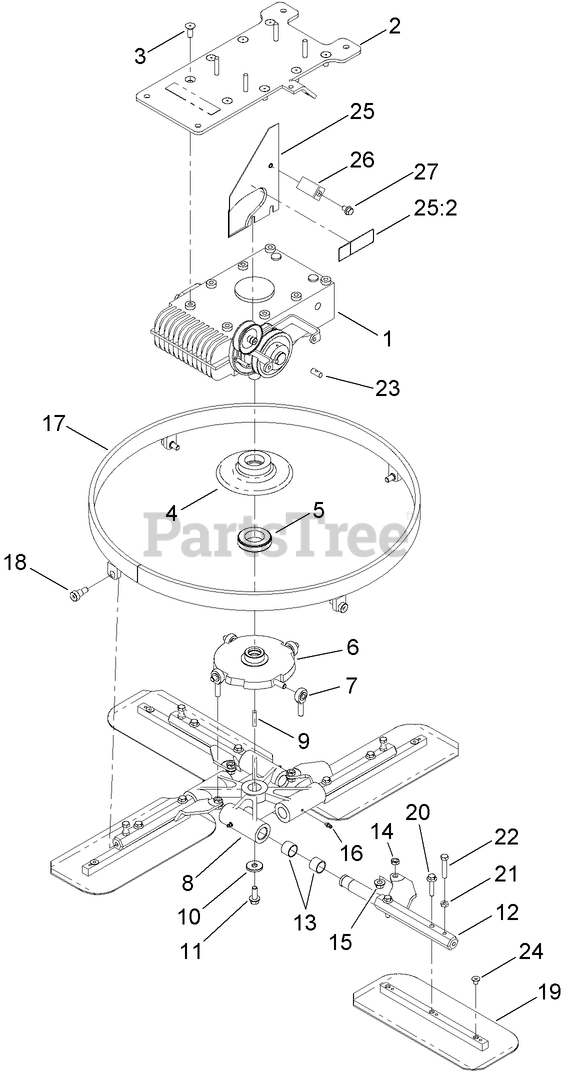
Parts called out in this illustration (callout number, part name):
1	GEARBOX ASM
2	BASE-ENGINE
3	SCREW
4	COVER-PLATE, THRUST
5	BEARING-BALL
6	PLATE-TILT
7	ROD-END
8	SPIDER-4 ARM
10	WASHER-FLAT
11	SCREW-HHF
12	ARM
13	BUSHING-SLEEVE, NYLON
14	NUT-HJ
15	NUT-LOCK
16	FITTING-GREASE
17	ROTATING-RING
18	SCREW-HSBH
19	BLADE-COMBINATION
20	SCREW-HHF
21	NUT-JAM
22	SCREW-HH
23	CABLE-TILT, PIVOT
24	CARPLUG-RED
25	REAR BELT GUARD ASM
25:2	DECAL-WARNING, SHIELDS
26	GUIDE-BELT
27	SCREW-FLANGE
